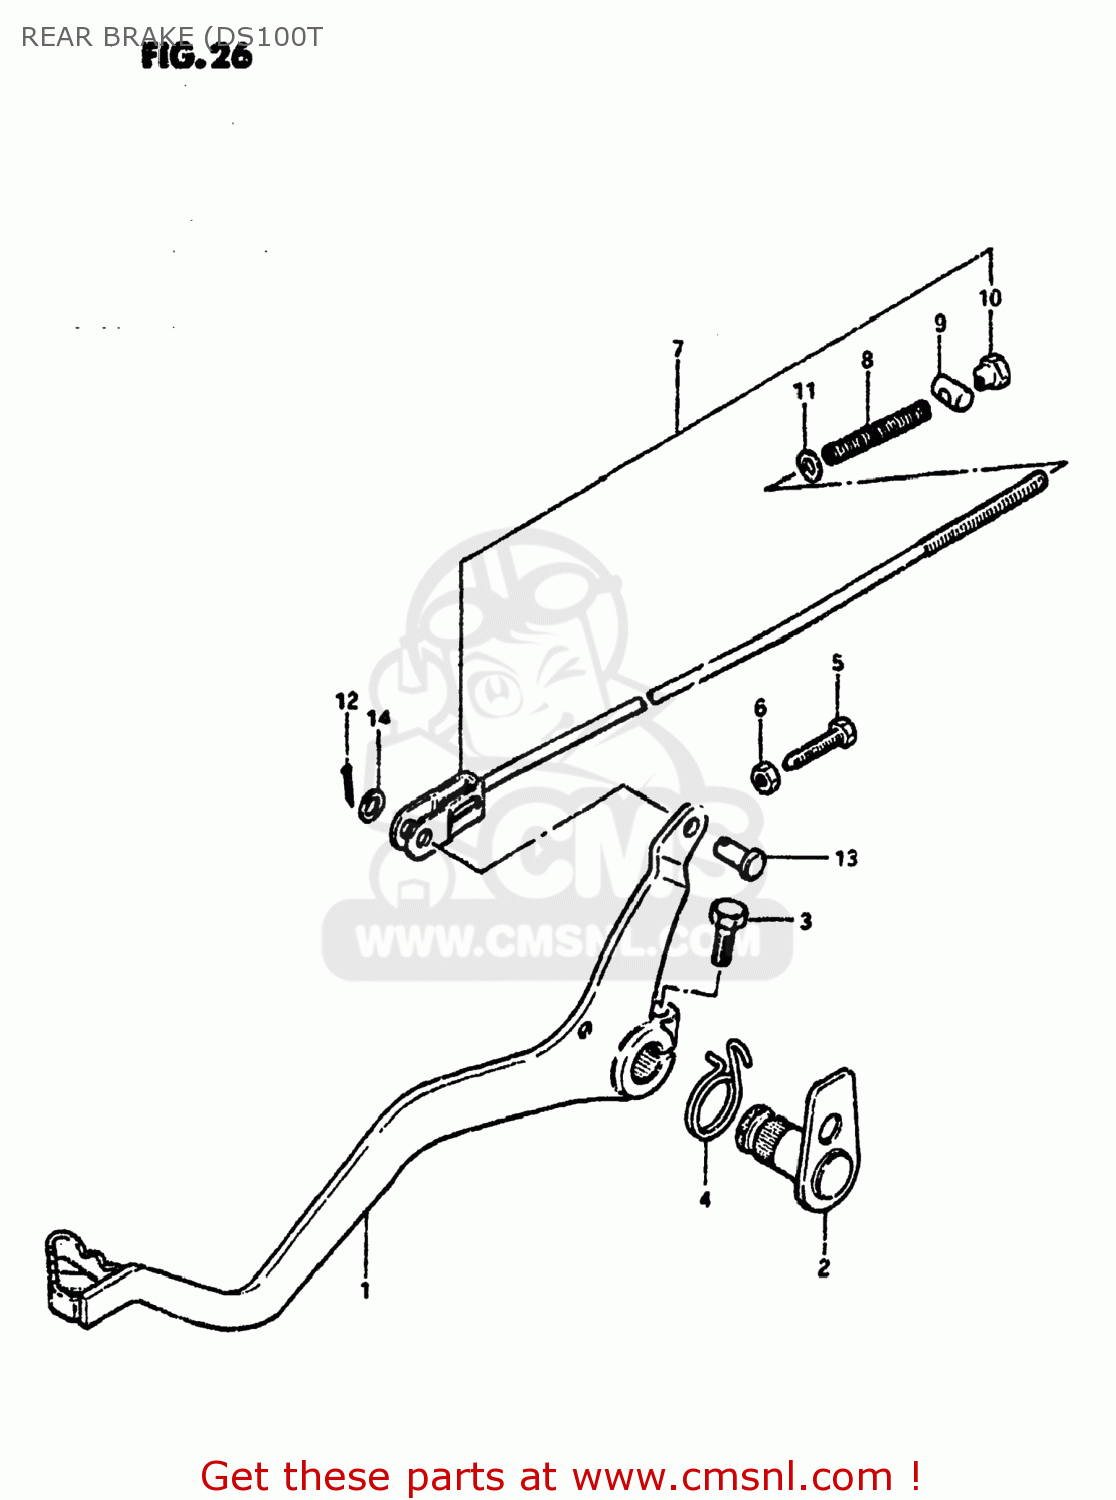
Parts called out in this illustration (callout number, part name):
1	PEDAL,BRAKE
2	ARM,BRAKE PEDAL
3	BOLT
4	SPRING
5	BOLT(6X23)
6	NUT
7	ROD ASSY,RR BRAKE
8	SPRING
9	PIN
10	NUT
11	WASHER
12	PIN 20X20
13	PIN(L:13.5)
14	WASHER
